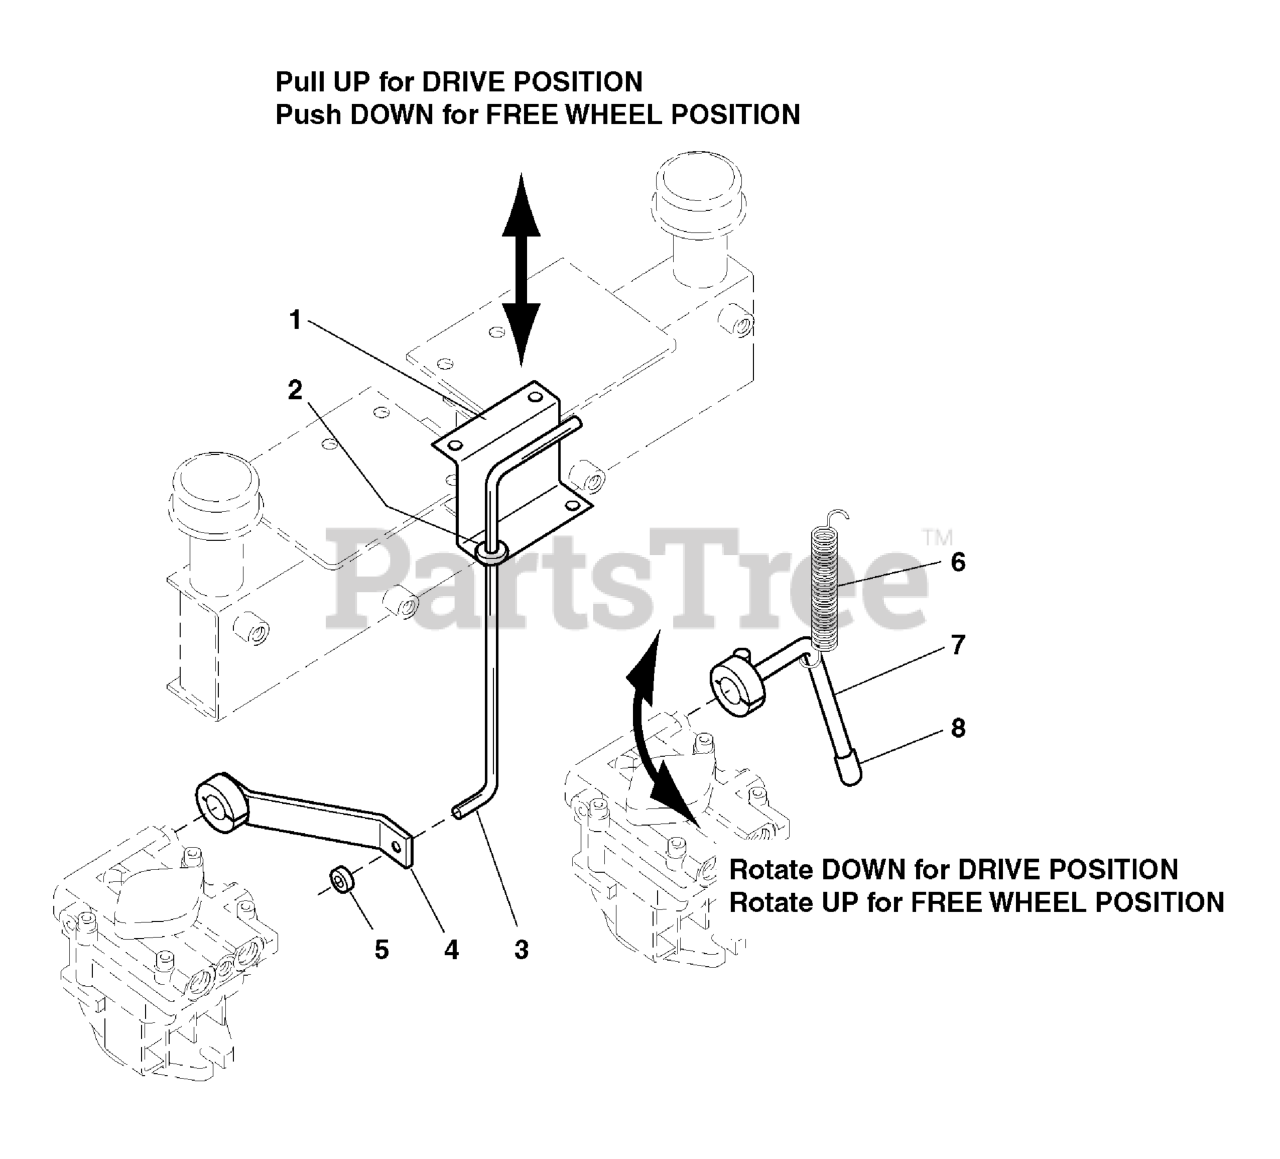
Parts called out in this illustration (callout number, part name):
1	ROD GUIDE PLATE
2	GROMMET
3	RELEASE ROD
4	ARM, Hydraulic Release-LH
5	COLLAR, Set, 1/4"
6	SPRING, Extension
7	ARM, Hydraulic Release-RH
8	VINYL CAP
